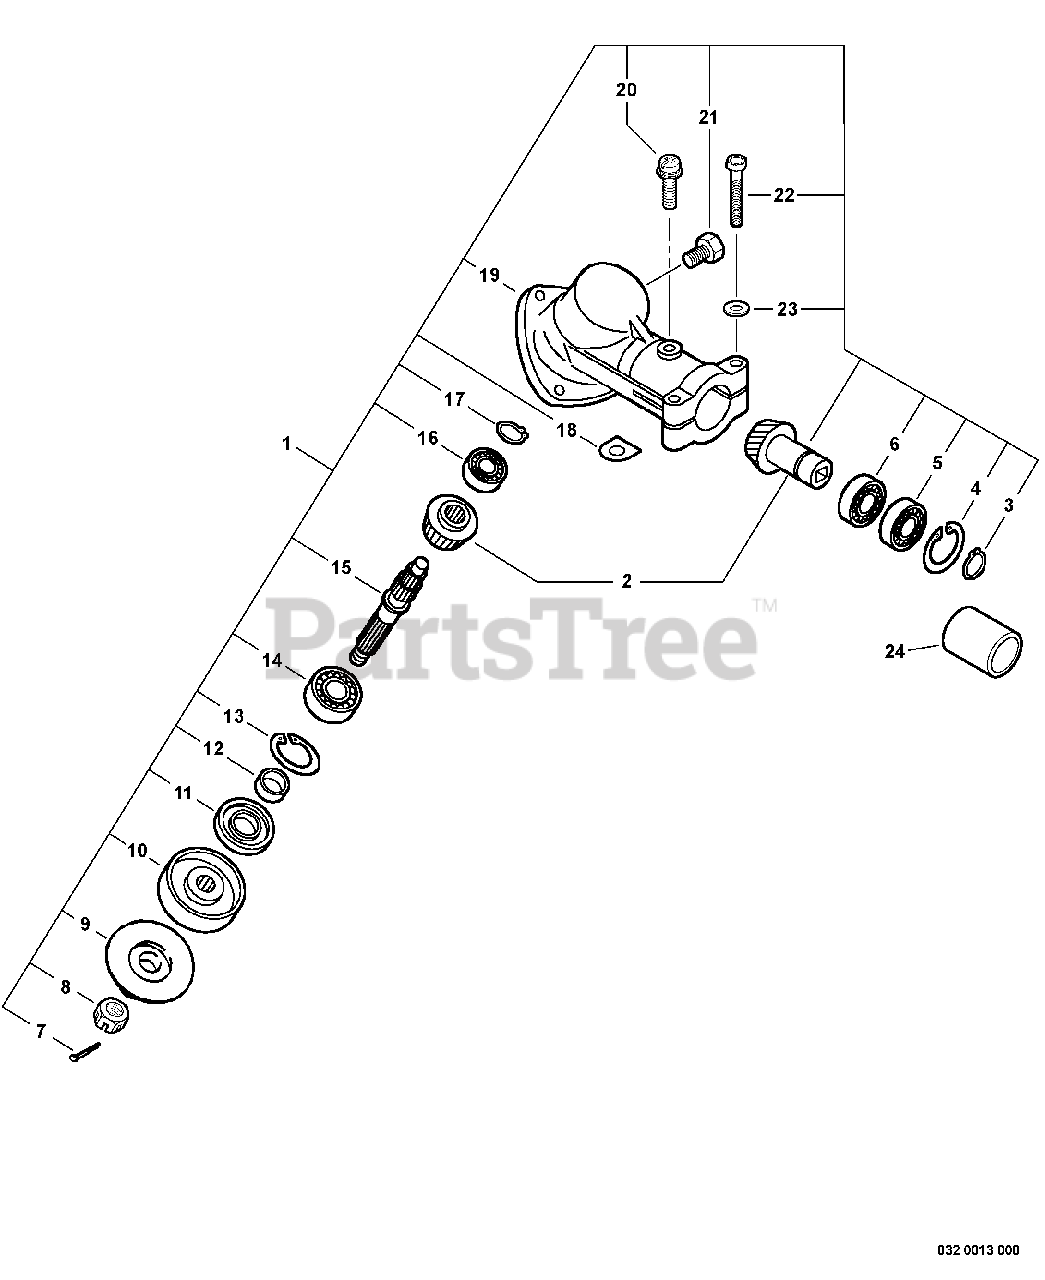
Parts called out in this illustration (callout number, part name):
1	GEAR CASE ASSY
2	GEAR SET - BEVEL
3	RING, RETAINING - 10
4	RING, RETAINING - 22
5	BEARING, BALL - 6900Z
6	BEARING, BALL - 6900
7	PIN, SPLIT - 2X22
8	LOCKNUT - LEFT HAND
9	ADAPTOR, BLADE - LOWER
10	ADAPTOR, BLADE - UPPER
11	SEAL, OIL
13	RING, RETAINING - 32
14	BEARING, BALL - 6201
15	GEAR - SHAFT
16	BEARING, BALL - 609
17	RING, RETAINING - 12
19	CASE, GEAR
20	SCREW - 5X12
21	BOLT - 8X8
22	BOLT - 5X30
23	WASHER - 5
